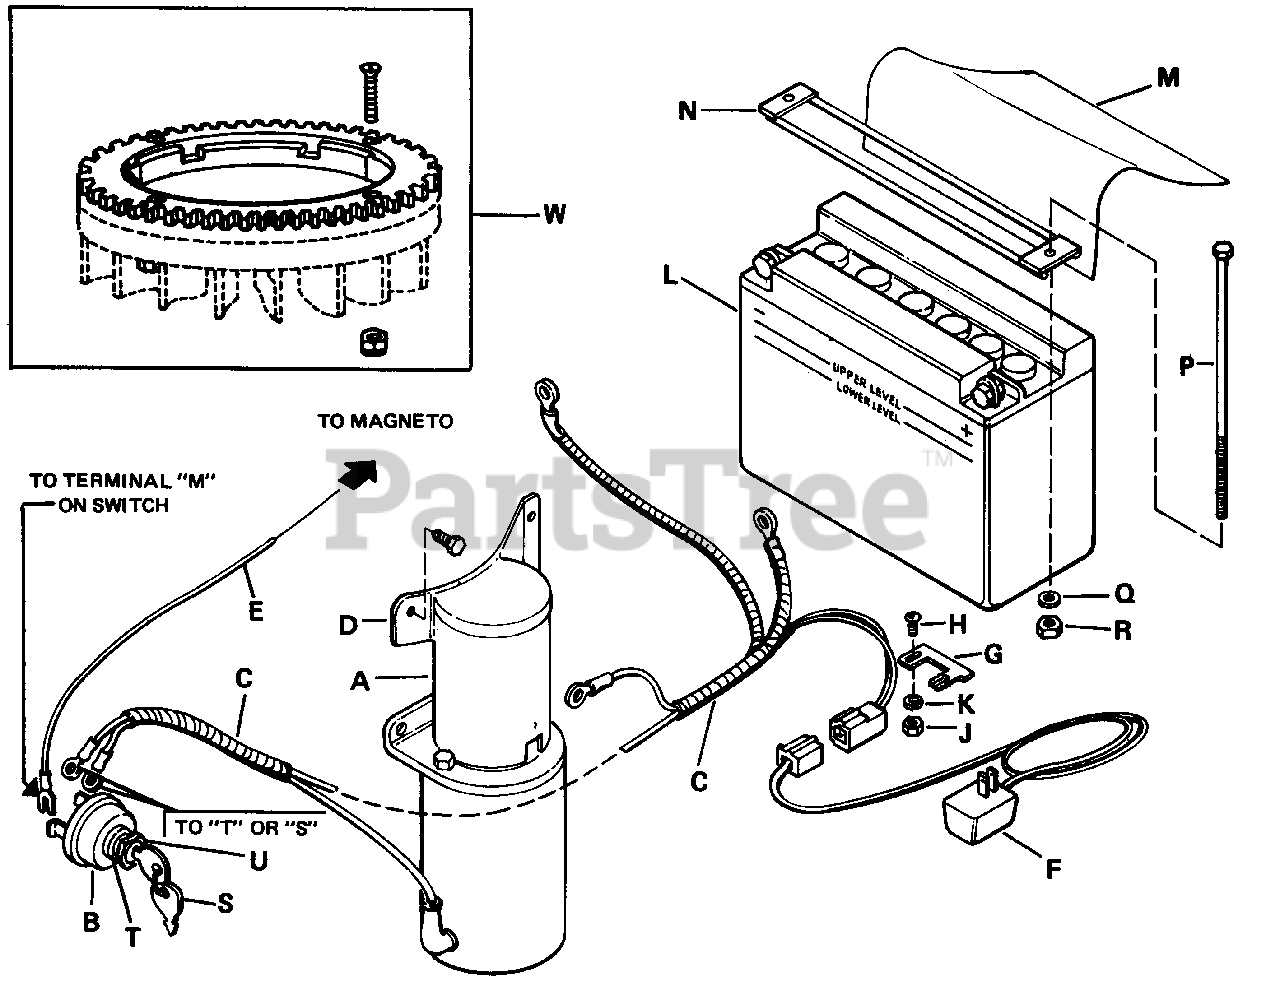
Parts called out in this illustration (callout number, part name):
A	Starter Kit
B	Switch w/Keys
C	Harness Assembly
D	Terminal Cover
F	Charger Assembly
G	Mounting Clip
H	Mach. Screw No. 10-32 N.F. x 1/2"
J	Full Hex. Nut No. 10-32 N.F.
K	Lock Washer No. 10 Ext. Type
M	Battery Insulation
N	Hold-Down Battery
P	Bolt 1/4" x 6-1/2" Lg.
Q	Lock Washer 1/4"
R	Full Hex. Nut 1/4"-20 N.C.
T	Lock Washer, 5/8 Int. Tooth
U	Hex Nut - Special
W	Ring Gear Assembly
